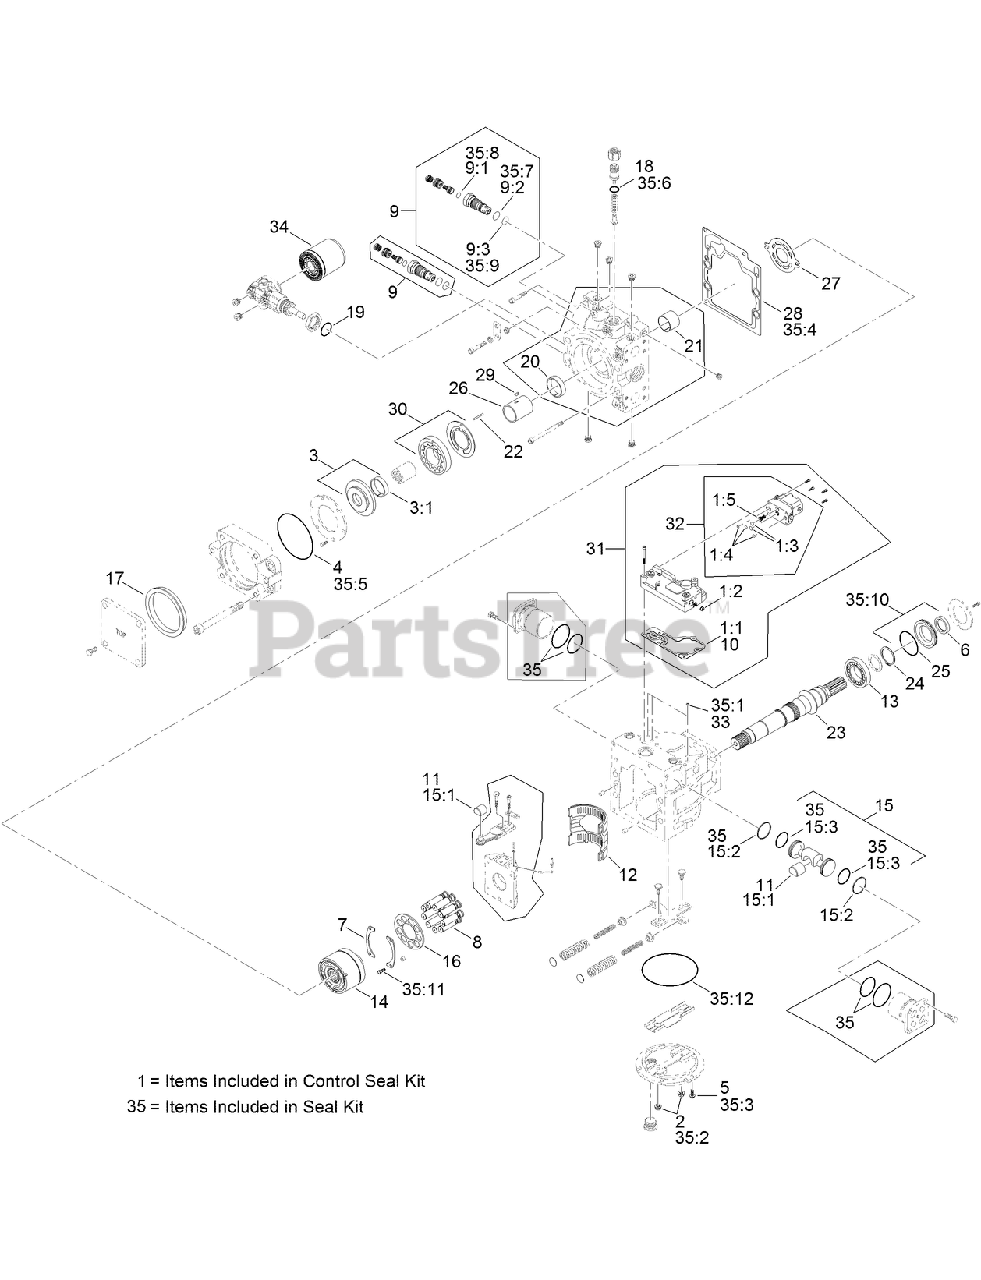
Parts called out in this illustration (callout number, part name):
1	CONTROL SEAL KIT
1:1	GASKET-CONTROL
1:2	NUT-SEAL
1:3	O-RING
1:4	O-RING
1:5	FILTER ASM
2	NUT-SEAL
3	CHARGE PUMP COVER ASM
3:1	BEARING-JOURNAL
4	O-RING
6	SEAL-LIP
7	BEARING-GUIDE, SLIPPER
8	PISTON-WELDED
9	MULTI FUNCTION VALVE ASM
9:1	O-RING
9:2	O-RING
9:3	O-RING
10	GASKET-CONTROL
11	BLOCK-SLIDER
12	CRADLE BEARING ASM
13	BEARING-ROLLER
14	CYLINDER BLOCK ASM
15	SERVO PISTON ASM
15:1	BLOCK-SLIDER
15:2	SEAL
15:3	O-RING
16	GUIDE-SLIPPER
17	SEAL-C PAD
18	O-RING
19	O-RING
20	BEARING-JOURNAL
21	BEARING-JOURNAL
23	SHAFT-13 TOOTH
24	RING-RETAINING
25	O-RING
26	SHAFT-PUMP, CHARGE
27	PLATE-VALVE
28	GASKET-CAP, END
30	CHARGE PUMP SET
31	E.D.C KIT
32	WEATHER PACK CONNECTOR KIT
33	SCREEN-FILTER, CONTROL
34	FILTER-CHARGE
35	OVERHAUL SEAL KIT
35:1	SCREEN-FILTER, CONTROL
35:2	NUT-SEAL
35:4	GASKET-CAP, END
35:5	O-RING
35:6	O-RING
35:7	O-RING
35:8	O-RING
35:9	O-RING
35:10	SHAFT SEAL ASM
35:11	Screw
35:12	O-RING
